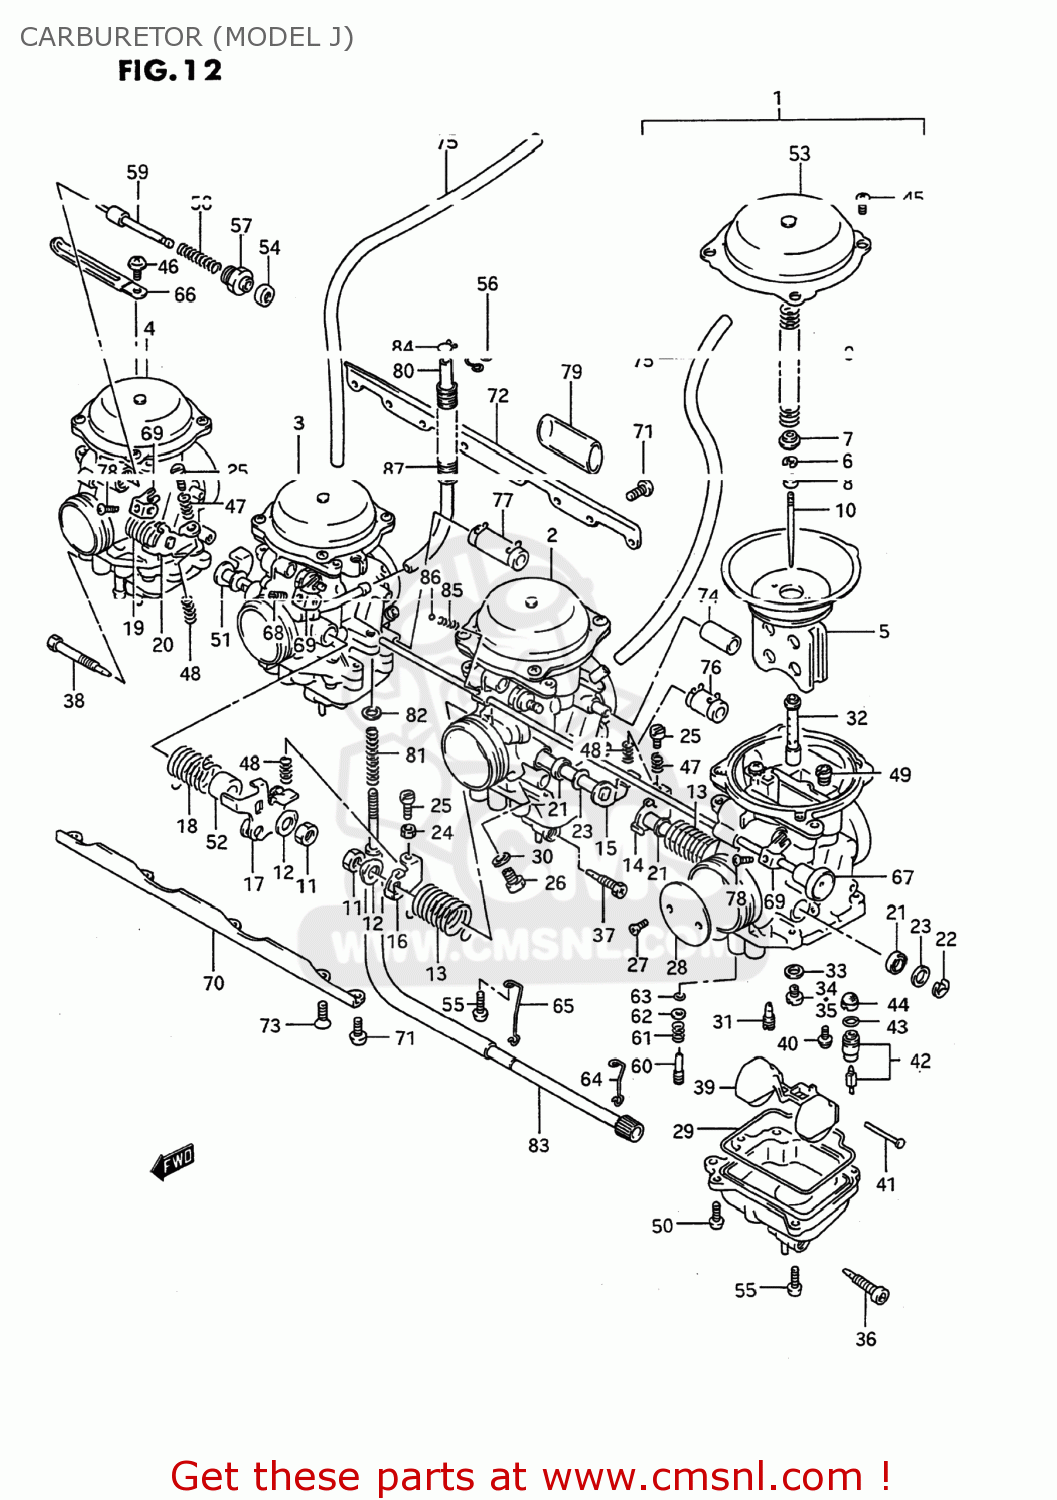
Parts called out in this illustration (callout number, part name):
1	CARBURETOR ASSY,LH
2	CARBURETOR ASSY,ML
3	CARBURETOR ASSY,MR
4	CARBURETOR ASSY,RH
5	DIAPHRAGM ASSY
6	CLIP
7	RING
8	RING
9	SPRING
10	NEEDLE,JET
11	NUT
12	WASHER
13	SPRING
14	SHAFT ASSEMBLY
15	SHAFT ASSEMBLY
16	LEVER
17	LEVER ASSEMBLY
18	SPRING
19	SPRING
20	SHAFT ASSEMBLY
21	SEAL
22	E RING
23	GASKET,THROTTLE SHAFT (NAS)
24	NUT,THROTTLE ROD
25	SCREW
26	SCREW
27	SCREW
28	VALVE,THROTTLE (130)
29	O RING,FLOAT CHAMBER
30	WASHER
31	JET(40)
32	JET,NEEDLE(P-9)
33	WASHER,NEEDLE NOZZLE
34	JET,MAIN(137.5)
35	JET,MAIN(135)
36	PLUG,DRAIN
37	PLUG
38	SCREW,DRAIN
39	FLOAT
40	SCREW
41	PIN,FLOAT
42	VALVE ASSY,NEEDLE
43	O-RING,NEEDLE VALVE
44	FILTER
45	SCREW
46	SCREW
47	SPRING
48	SPRING,THROTTLE SCREW
49	JET
50	SCREW
51	SHAFT ASSEMBLY
52	RING
53	COVER,DIAPHRAGM
54	CAP,STARTER VALVE
55	SCREW
56	CLIP
57	GUIDE SCREW,PLUNGER
58	SPRING
59	PLUNGER ASSY
60	SCREW,PILOT
61	SPRING
62	WASHER
63	O RING,PILOT AIR SCREW
64	CLIP
65	CLIP
66	CLIP
67	SHAFT ASSEMBLY
68	SCREW
69	LEVER
70	PLATE
71	SCREW
72	PLATE
73	SCREW(5X14)
74	HOSE,CARBURETOR
75	HOSE
76	HOSE SET (3X5X18)
77	HOSE ASSY
78	SCREW
79	HOSE(16X19X100)
80	HOSE
81	SPRING
82	WASHER
83	ADJUSTER
84	CLIP
85	SPRING
86	BALL,CARBURETOR
87	HOSE
